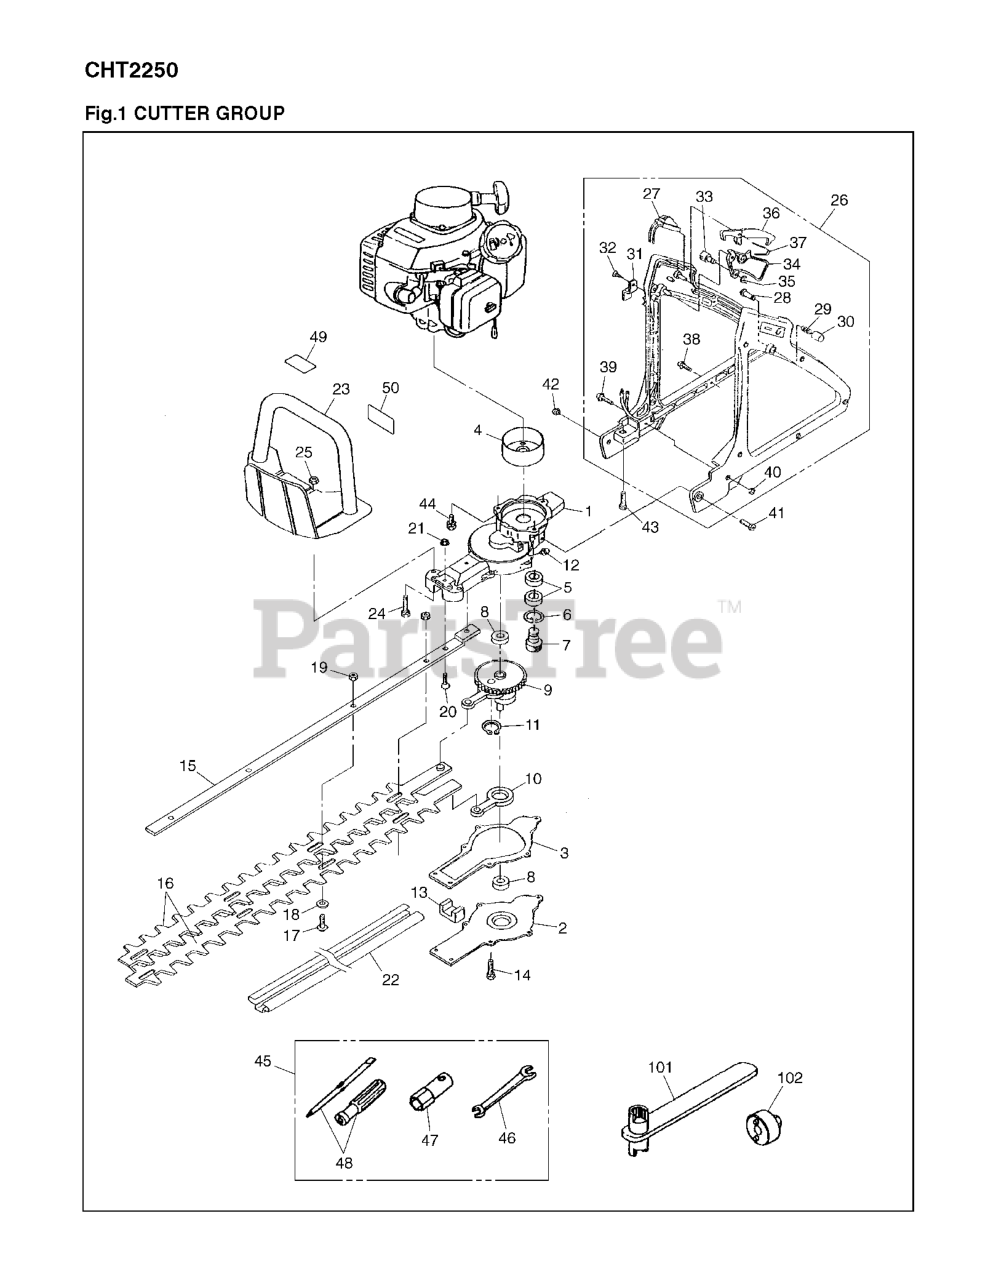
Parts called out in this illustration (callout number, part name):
1	GEARCASE
6	RING, SNAP
8	BEARING
9	GEAR COMPL
11	RING, SNAP, M25 x 1.2
14	BOLT (RPLS 020510512)
15	PLATE, GUIDE
16	BLADE (22")
17	SCREW
22	COVER, BLADE
23	HANDLE, FRONT
26	HANDLE.REAR-A
27	SWITCH-A
33	WIRE END
45	TOOL SET
101	WRENCH(B)
